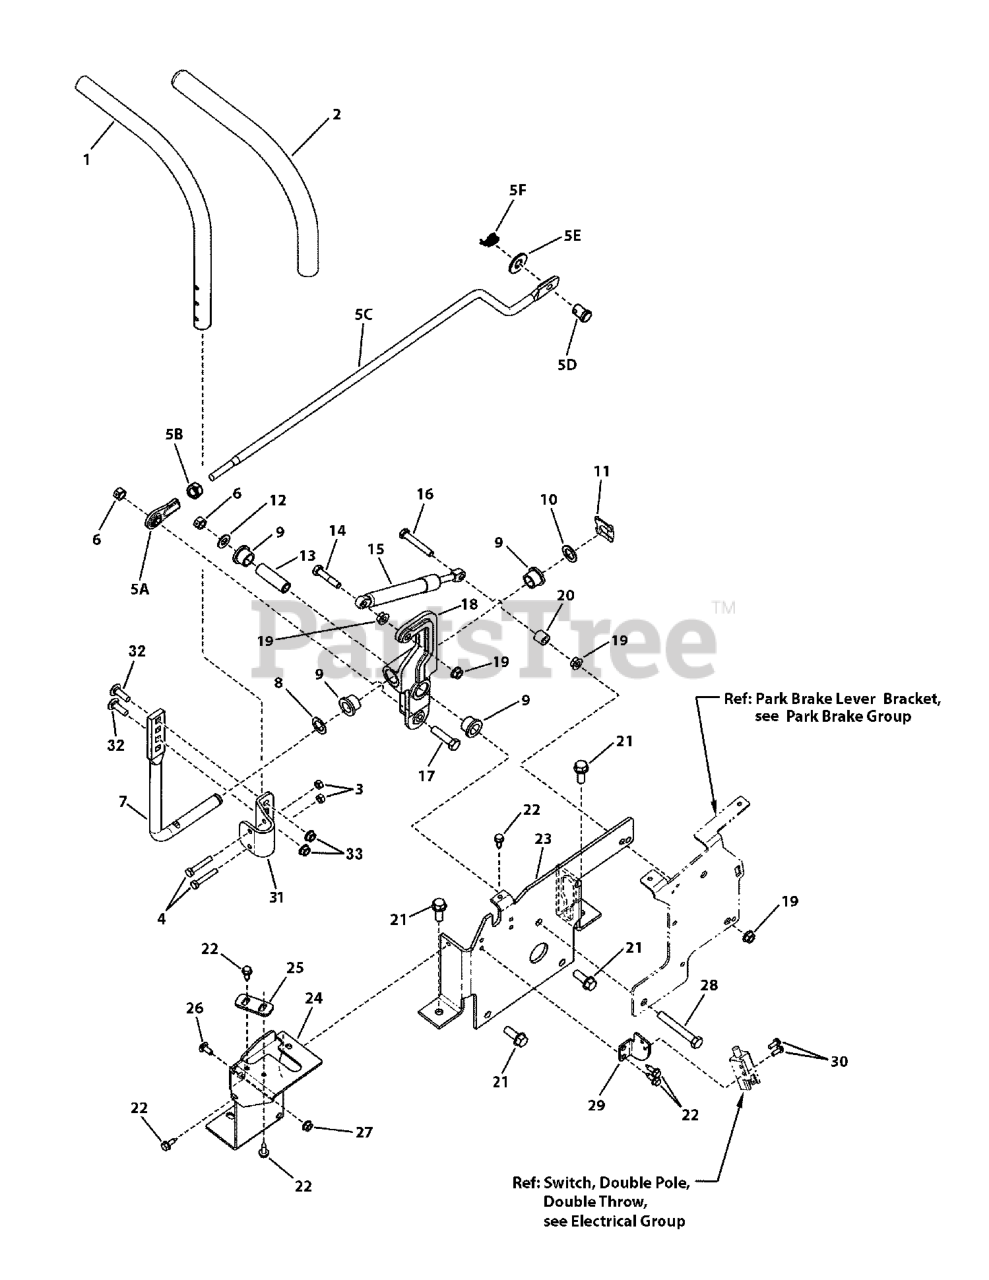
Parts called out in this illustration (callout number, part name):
1	HANDLE, Adjustable
2	GRIP, Handle
3	NUT, Hex, Center Lock, 1/4-20, GR 5
4	CAPSCREW, Hex Head, 1/4-20 x 1-1/2, GR 5
5A	ROD END, (3/8-24 thread)
5B	NUT, Hex, 3/8-24, GR 5
5C	ROD, Link Forward/Reverse
5D	CLEVIS PIN, 7/16 x 1
5E	WASHER, Flat, 7/16
5F	COTTER PIN, Self Locking, 1/2
6	NUT, Hex, Center Lock, 3/8-16, GR 5
7	ROD, Handle, Adjustable
8	WASHER, Flat, 5/8
9	BUSHING, Bronze, 5/8 x 5/8
10	WASHER, Nylon, 5/8 ID x 1" OD
11	CLIP, Spring, 5/8 OD Shaft
12	WASHER, Flat, 3/8 (SAE)
13	SPACER, Sleeve, RZT
14	CAPSCREW, Hex Head, 5/16-18 x 1-1/2,GR 5
15	DAMPENER, Control
16	CAPSCREW, Hex Head, 5/16-18 x 2, GR 5
17	CAPSCREW, Hex Head, 3/8-16 x 1-1/2, GR 5
18	ARM, Control, Die Cast, LH
19	NUT, Hex Center Lock, 5/16-18
20	SPACER, .625 OD x .380 ID x .564 L
21	SCREW, Hex Washer Head, Self-Tap, 3/8-16 x 1
22	SCREW, Hex Washer Head, Self-Tap, 1/4-20 x 3/4
23	BRACKET, Control, LH
24	BRACKET, Guide, Stick, Control, LH
25	PLATE, Fwd/Rev Adjust
26	BOLT, Carriage, Short Neck, 1/4-20 x 5/8, GR 5
27	NUT, Hex Flange Lock, 1/4-20
28	CAPSCREW, Hex Head, 3/8-16 x 3-1/4, GR 5
29	BRACKET, Switch
30	SCREW, #10-24 x 1/2" Hex Washer Self-Tap (Torx)
31	BRACKET, Handle Adjustment
32	BOLT, Carriage, 5/16-18 x 1, GR 5
33	NUT, Hex Flange Two-Way Lock, 5/16-18
